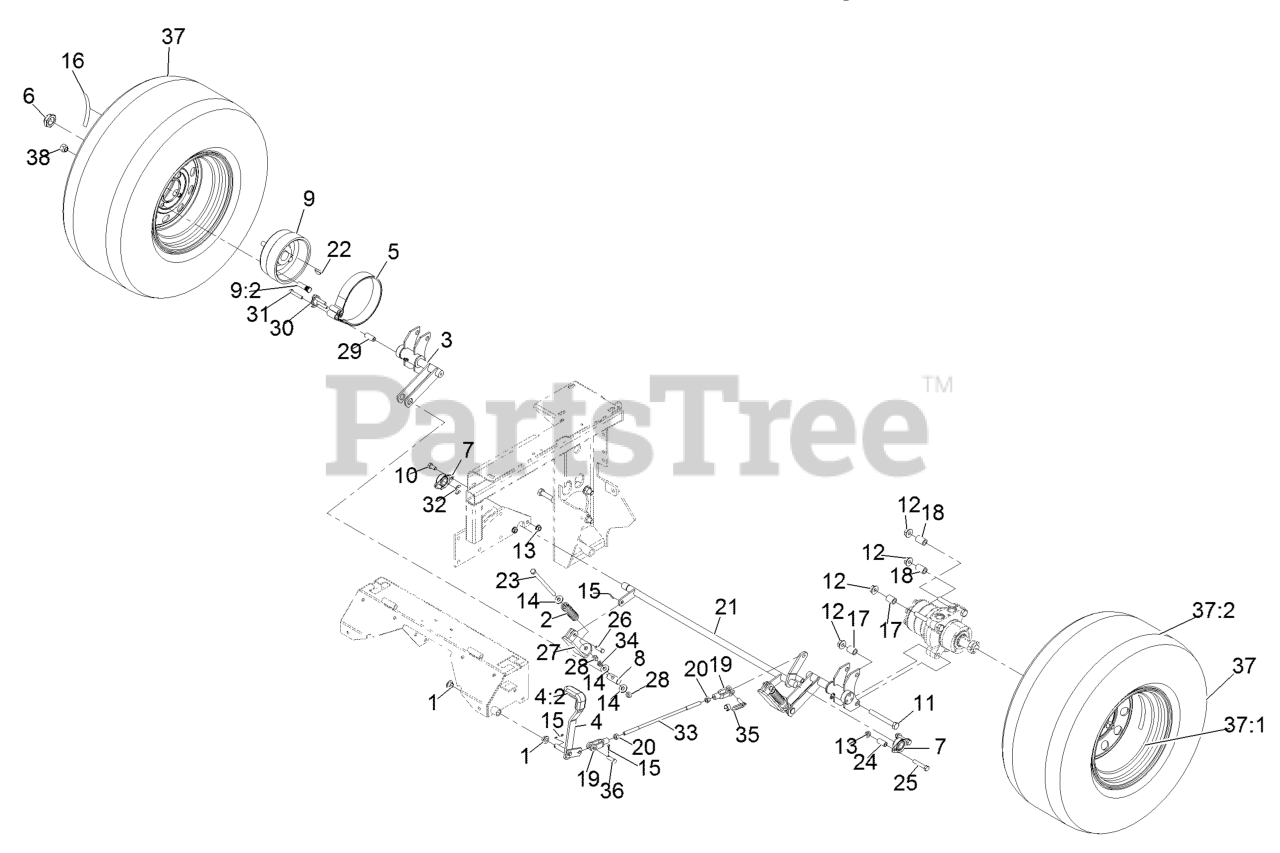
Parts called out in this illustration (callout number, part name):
1	BEARING-CONTROL
2	SPRING-COMPRESSION
3	BRAKE-WIDE
4	BRAKE LEVER AND GRIP ASM
4:2	GRIP-LEVER
5	BAND,BRAKE
6	LOCKNUT
7	BEARING-FLANGE, SIDE
8	PIN-TRUNION
9	HUB W/STUDS ASM
9:2	STUD-WHEEL
10	SCREW-HH
11	SCREW-HH
12	NUT-HHF
13	NUT-HHF, WHIZ
14	WASHER-FLAT
15	PIN-COTTER
16	DECAL-TORQUE, WHEEL HUB LUG
17	SPACER-WHEEL, SHORT
18	SPACER-WHEEL, LONG
19	YOKE-LINKAGE, BRAKE
20	NUT-HEX
21	SHAFT-BRAKE
22	KEY-WOODRUFF
23	BOLT-TAP, HH
24	SPACER-RETAINER, BRAKE
25	SCREW-HH
26	PIN-CLEVIS
27	LINKAGE-BRAKE, LOWER
28	NUT-LOCK, NI
30	RETAINER-BAND, BRAKE
31	SCREW-HH
33	ROD-BRAKE
34	NUT-JAM
35	PIN-SPRING, CLEVIS
36	PIN-CLEVIS
37	WHEEL AND TIRE ASM
38	NUT-LUG
